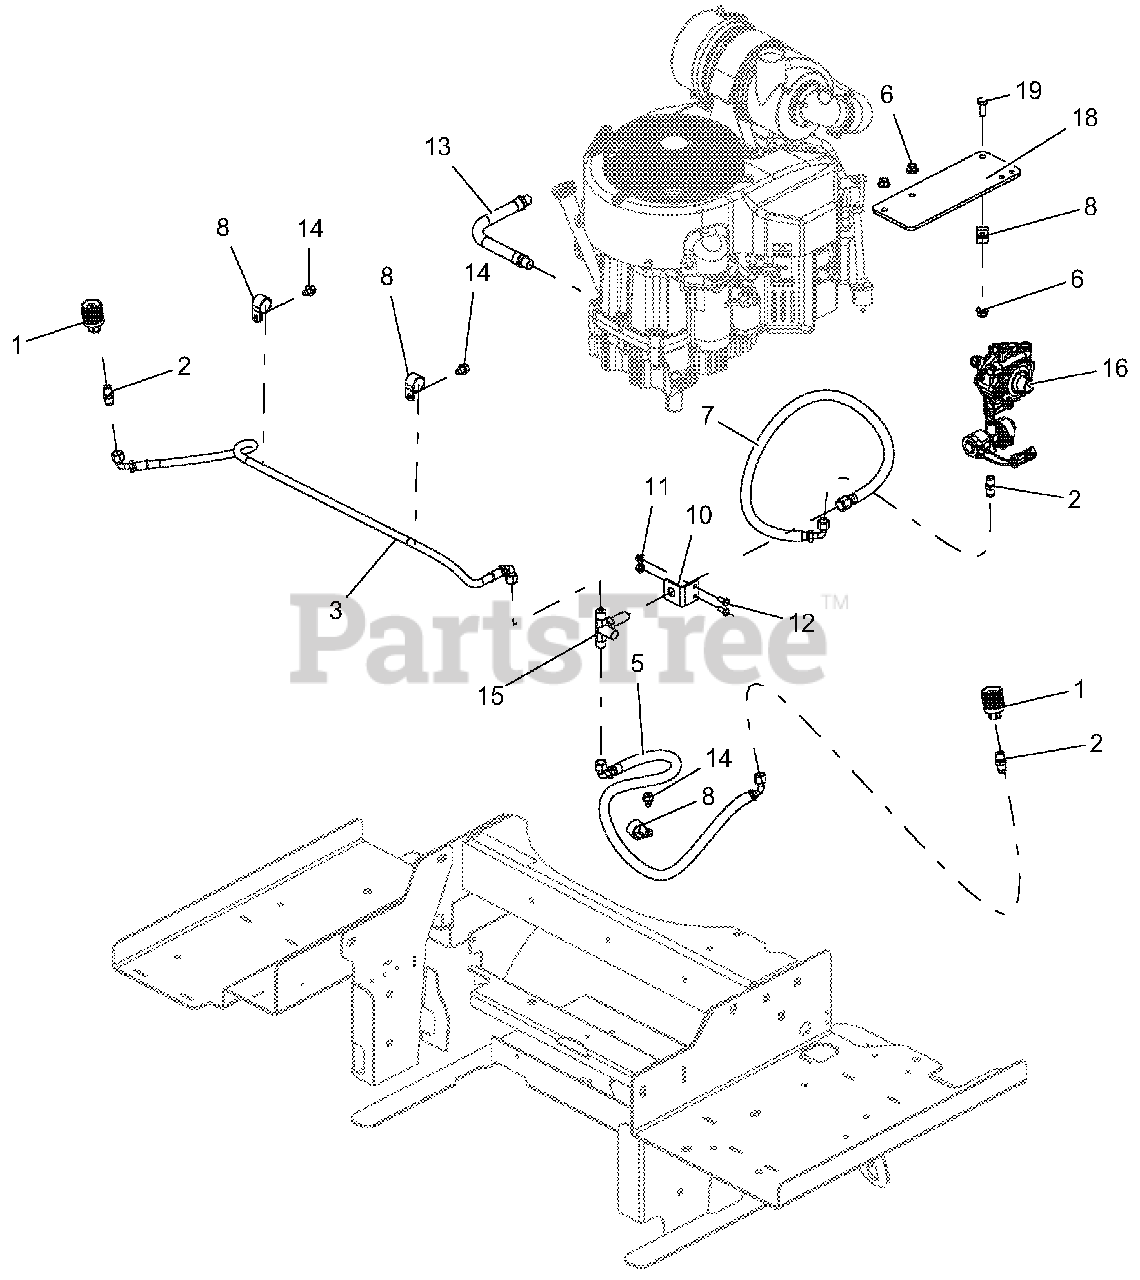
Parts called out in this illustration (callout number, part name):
1	FTG, LPG TANK COUPLER -LH THRD
2	FTG, ADPTR 1/4MNPT X 5/8MJIC
3	HOSE, LPG SS25UL-6-4-6-45"
5	SLV, ABRASION RESISTANT
6	NUT-LK-NYL-FLG .38-16 YWZC
7	SLV, ABRASION RESISTANT
8	CLAMP, CUSHIONED STEEL REV
10	BRKT, TEE VALVE- MOUNTING
11	NUT, LK-TOP-FLG .25-20 YWZC
12	BLT-HEX .25-20X.63 GR5 YWZC
13	HOSE, HYD .38-11-0K M6N0-M6NO
14	SCR-TAP .38-16X.50 HWH TR YWZ
15	VALVE, SHERWOOD T PV3866 LPG
16	SEE ENGINE SERVICE PARTS
18	PLATE, REGULATOR MOUNGT, E
19	BLT-HEX .38-16X1.00 GR5 YWZC
